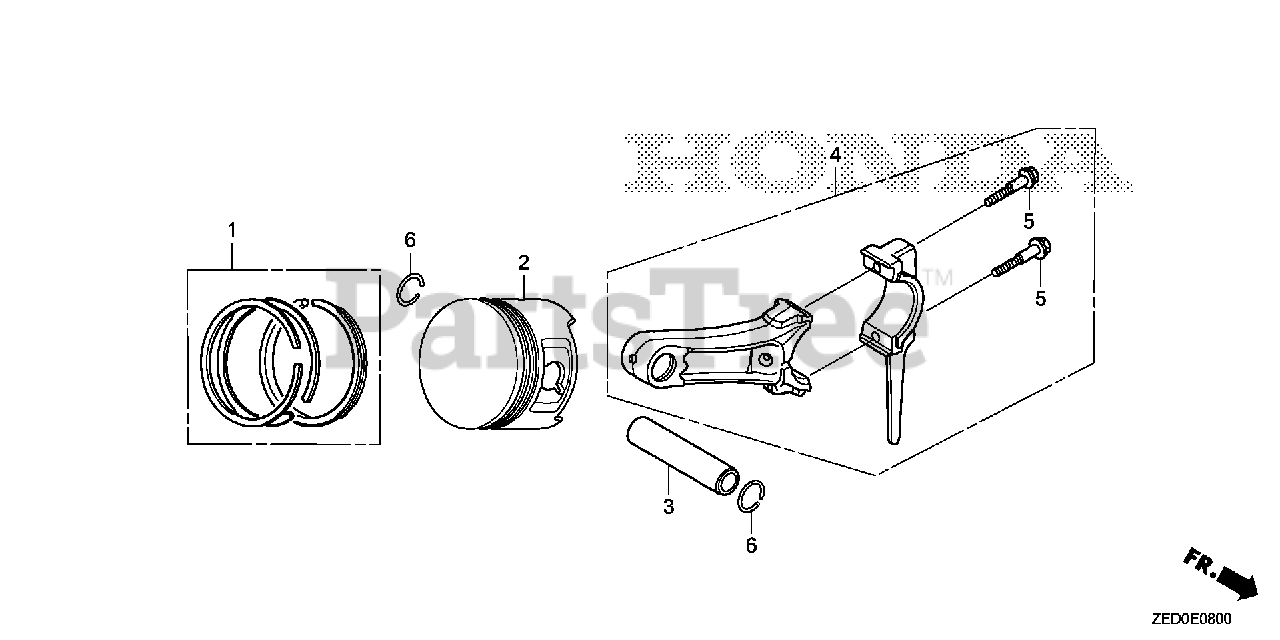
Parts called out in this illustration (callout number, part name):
1	RING SET, PISTON (STD) (TPR)
1	RING SET, PISTON (STD) (RIKEN) (NA USE ALT:13010-Z1T-931)
1	RING SET, PISTON (0.25) (TPR)
1	RING SET, PISTON (0.25) (RIKEN) (NA USE ALT:13011-Z1T-931)
1	RING SET, PISTON (0.50) (TPR)
1	RING SET, PISTON (0.50) (RIKEN) (NA USE ALT:13012-Z1T-931)
1	RING SET, PISTON (0.75) (TPR)
1	RING SET, PISTON (0.75) (RIKEN) (NA USE ALT:13013-Z1T-931)
2	PISTON (STD)
2	PISTON (0.25)
2	PISTON (0.50)
2	PISTON (0.75)
3	PIN, PISTON
4	ROD ASSY., CONNECTING (UNDER SIZE)
4	ROD ASSY., CONNECTING
5	BOLT, CONNECTING ROD (6X34.5)
6	CLIP, PISTON PIN (18MM)
